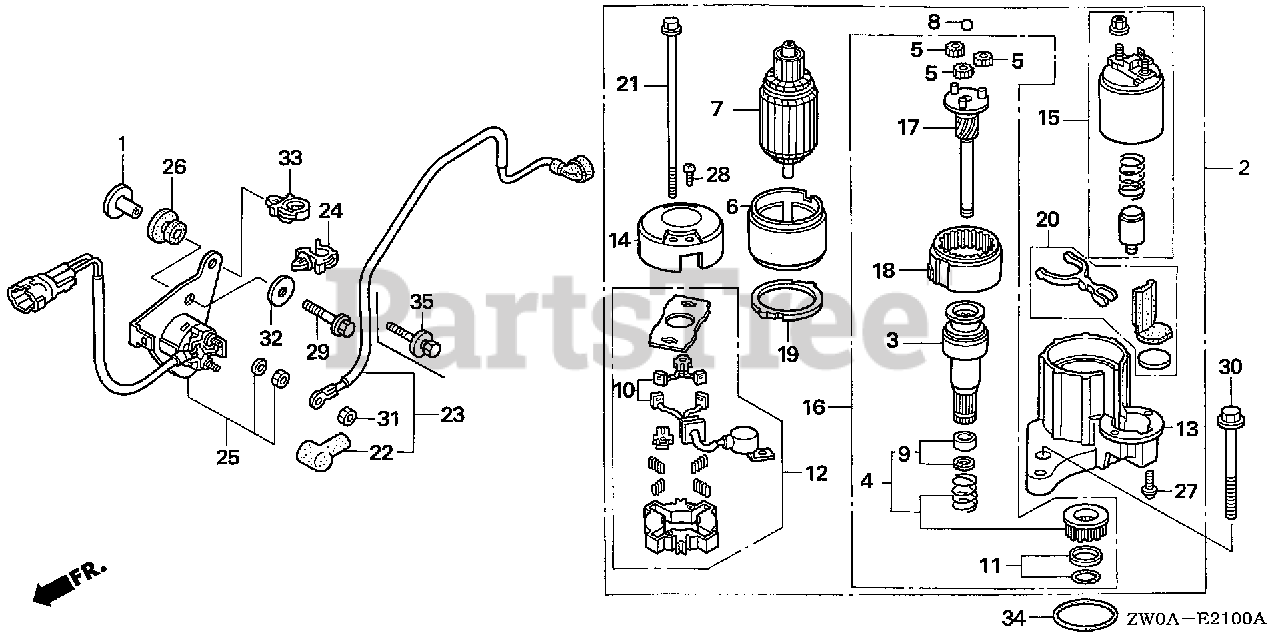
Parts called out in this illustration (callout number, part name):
1	COLLAR, FUEL TANK MOUNTING
2	STARTER MOTOR ASSY.
3	CLUTCH, OVERRUNNING
4	GEAR SET, PINION
5	GEAR ASSY., PLANETARY
8	BALL, STEEL
9	STOPPER SET, PINION
11	STOPPER SET, SLEEVE
12	HOLDER, BRUSH
13	BRACKET, FR.
14	BRACKET, RR.
15	SWITCH ASSY., MAGNET
16	SHAFT ASSY., CLUTCH
17	SHAFT ASSY., GEAR
18	GEAR ASSY. (INNER)
21	BOLT A, THROUGH
22	COVER, TERMINAL
23	WIRE, MAGNETIC SWITCH
24	CLAMP, WIRE
25	SWITCH ASSY., STARTER MAGNETIC
26	RUBBER A, NUMBER BRACKET CUSHION
27	SCREW, PAN (6X22) (SPECIAL)
28	SCREW, PAN (5X8)
29	BOLT, FLANGE (6X25)
30	BOLT, FLANGE (10X90)
31	NUT, HEX. (6MM)
32	WASHER, PLAIN (6MM)
33	CLIP, HARNESS
34	O-RING (54.4X3.1)
